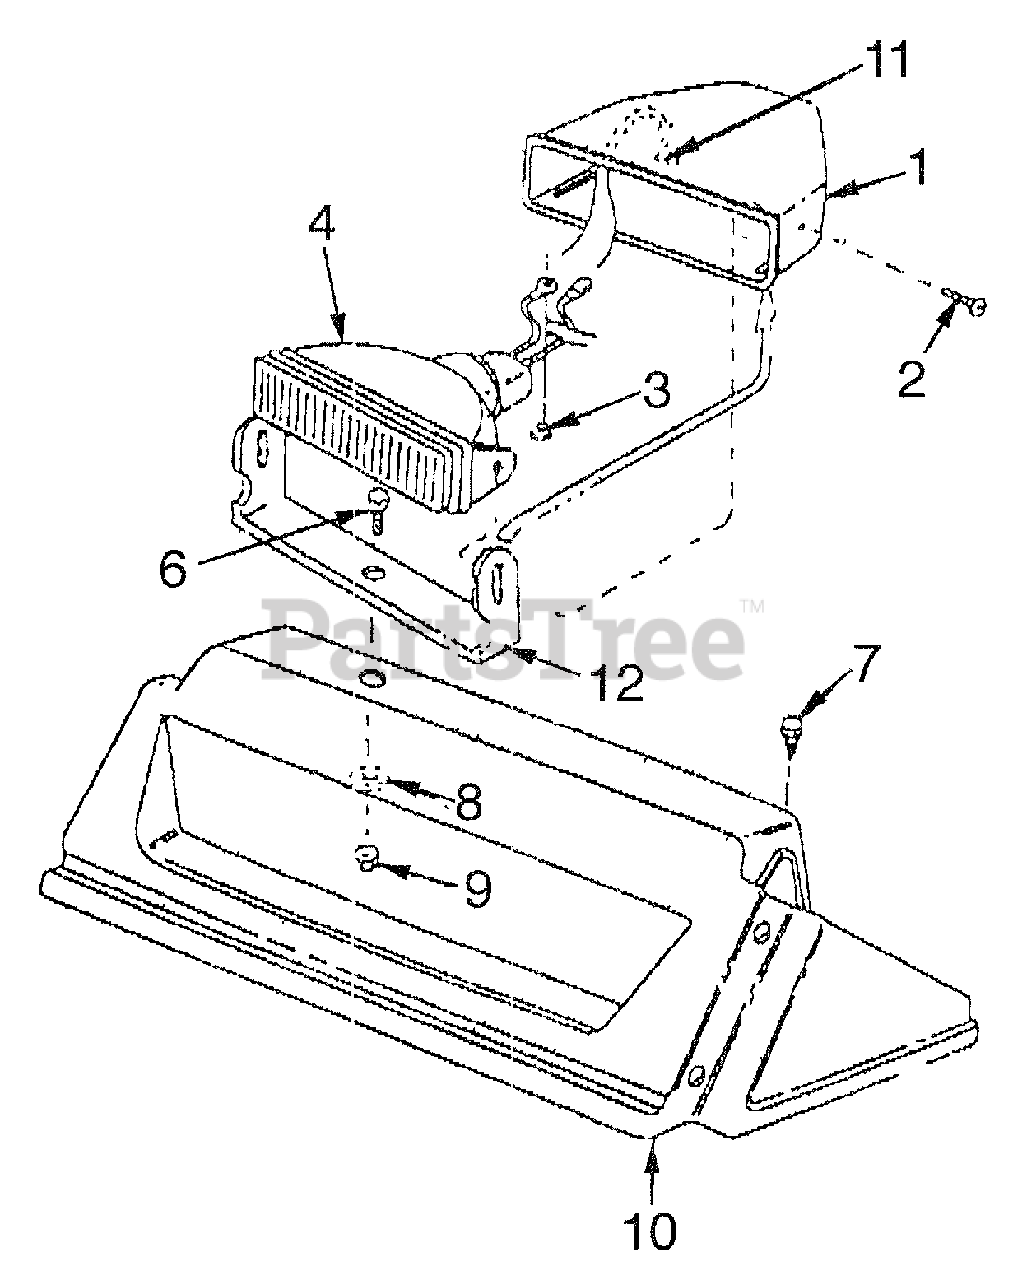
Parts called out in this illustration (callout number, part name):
1	Halogen Lamp Housing
2	Phillips Pan Head Screw M 4 x 16
3	Hex Sems Nut 1/4-20
4	Lamp/Lens Housing Ass'y
4	Halogen Light Wire Harness
4	#890 Halogen Bulb
6	Carriage Bolt 5/16-18 x .75
7	Pan Head B-Tapp Screw #10
8	Fl-Wash .344 ID x .88 OD
9	Hex Ins L-Nut 5/16-18
10	Handle Panel
11	Grommet .38 ID x .50 OD x 12
12	Lamp Mounting Bracket
